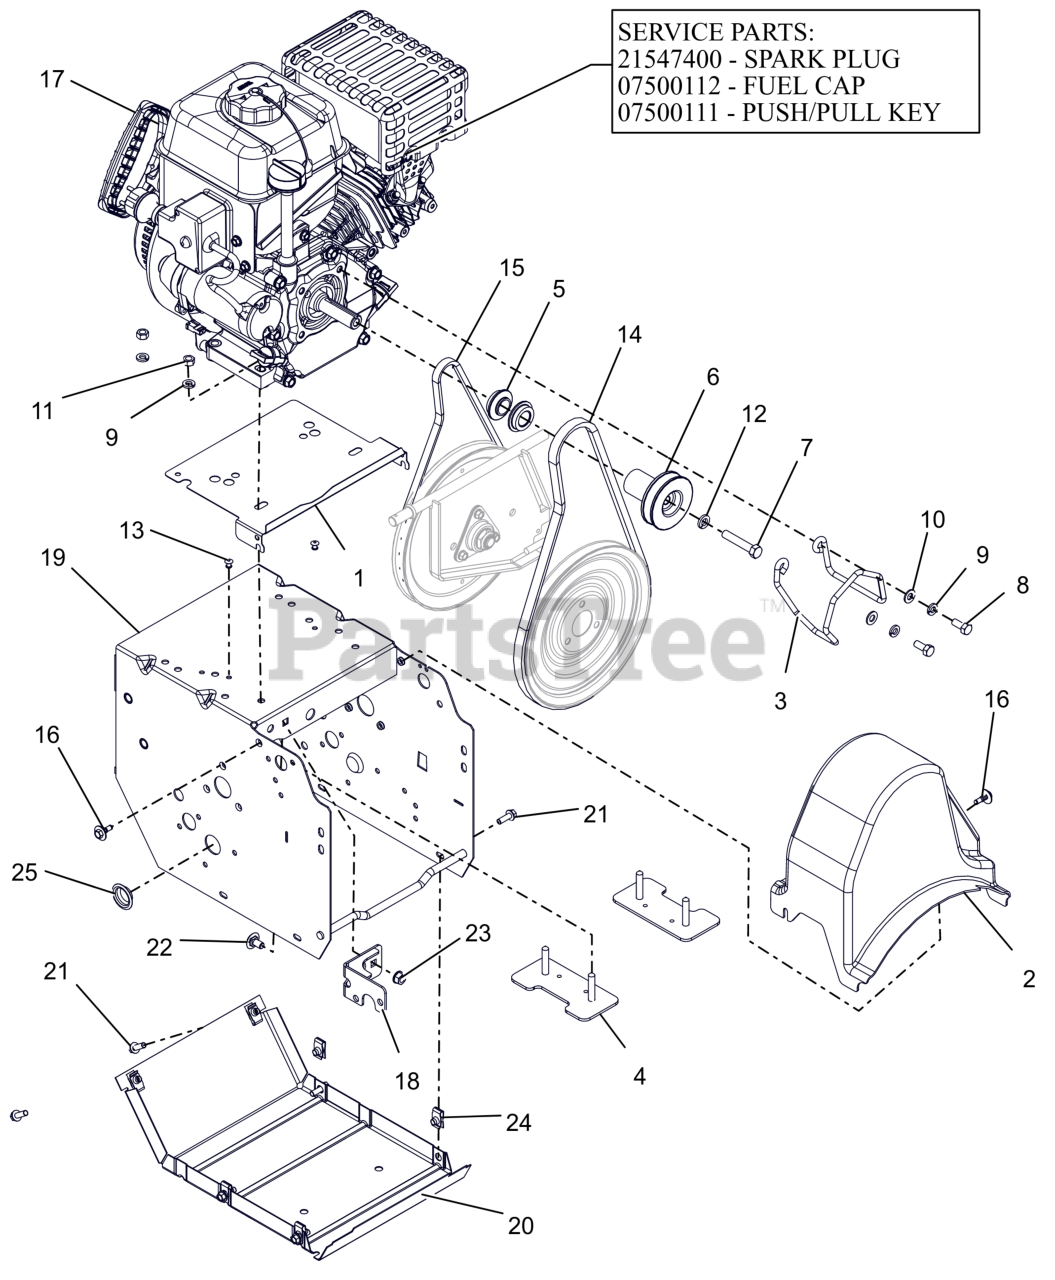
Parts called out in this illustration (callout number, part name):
1	BAFFLE, COMPACT
2	COVER, COMPACT BELT
3	FINGER, BELT
4	STRAP, ENGINE BOLT-WELDMENT
5	SHEAVE, TRACTION HALF (KEYLESS)
6	SHEAVE, AUGER 3/4 - PM
7	BLT, HEX .38-24X2.00 G5 ZCC
8	BLT, HEX .31-24X.750 G5 ZCC
9	WSHR, LK-HVY .312X.097 ZCC
10	WSHR,FLT .344X.688X.065 ZCC
11	NUT, HEX .312-18 ZCC
12	WSHR, LK-HVY .375X.115 ZCC
13	RVT, POP .1875 ZCC
14	V-BELT, HA-RAW EDGE
15	V-BELT, 3L-WRAPPED
16	SCR-TAP .25-20X.5 CAPTIVE
17	ENGINE, ARIENS AX208 240V/60W
17	PLUG, SPARK
17	CAP, FUEL TANK BLACK
17	KEY, PUSH/PULL LCT (2/PACKAGE)
18	WELDMENT, FRAME BRACKET
19	FRAME, MAIN
20	COVER, BOTTOM
21	BLT, HWH .25-20X.75 G5 ZCC
22	BLT, RHSSN .31-18X.625 G5 ZCC
23	NUT-LK-TOP-FLG .312-18 GF ZCC
24	NUT-RTNR .25-20X.56
25	PLUG, HOLE - 1.00" FLEXTEMP
